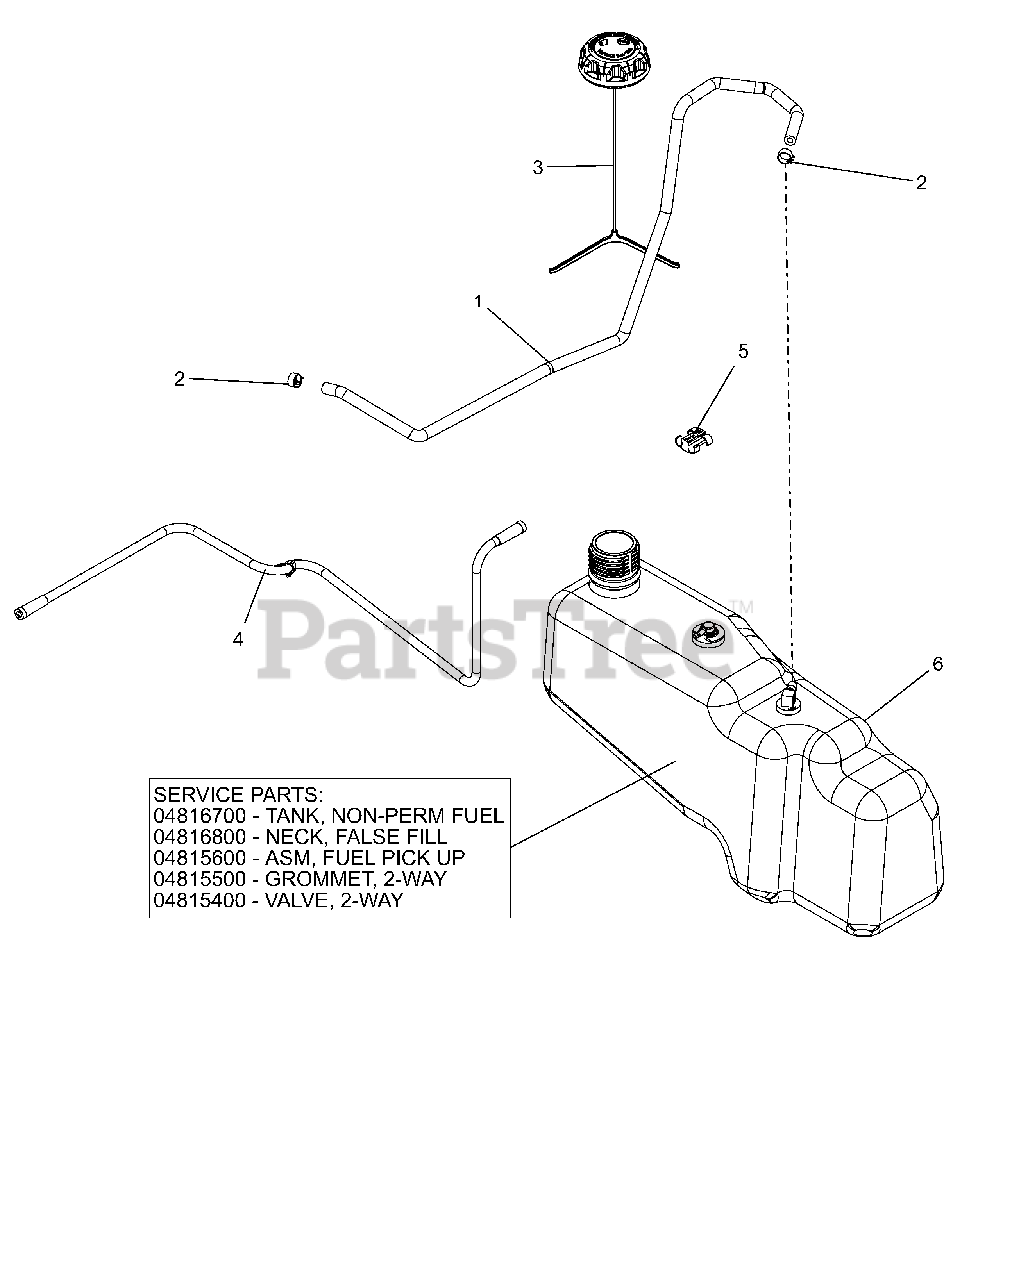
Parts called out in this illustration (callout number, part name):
1	HOSE, .25 LOW-PERM BULK GAS
2	CLAMP, FUEL LINE
3	CAP, FUEL VENT-IN 2.25" RATCH.
4	LINE, FUEL VENT KAWI
5	CLIP, T, .38-.50
6	ASM,TANK NON-PERM FUEL
6	TANK, ZOOM/ZT NON-PERM, FUEL
6	NECK, FALSE FILL ZOOM/ZT
6	ASM, FUEL PICK-UP ZOOM/ZT 2015
6	GROMMET, 2-WAY
6	VALVE, 2-WAY
